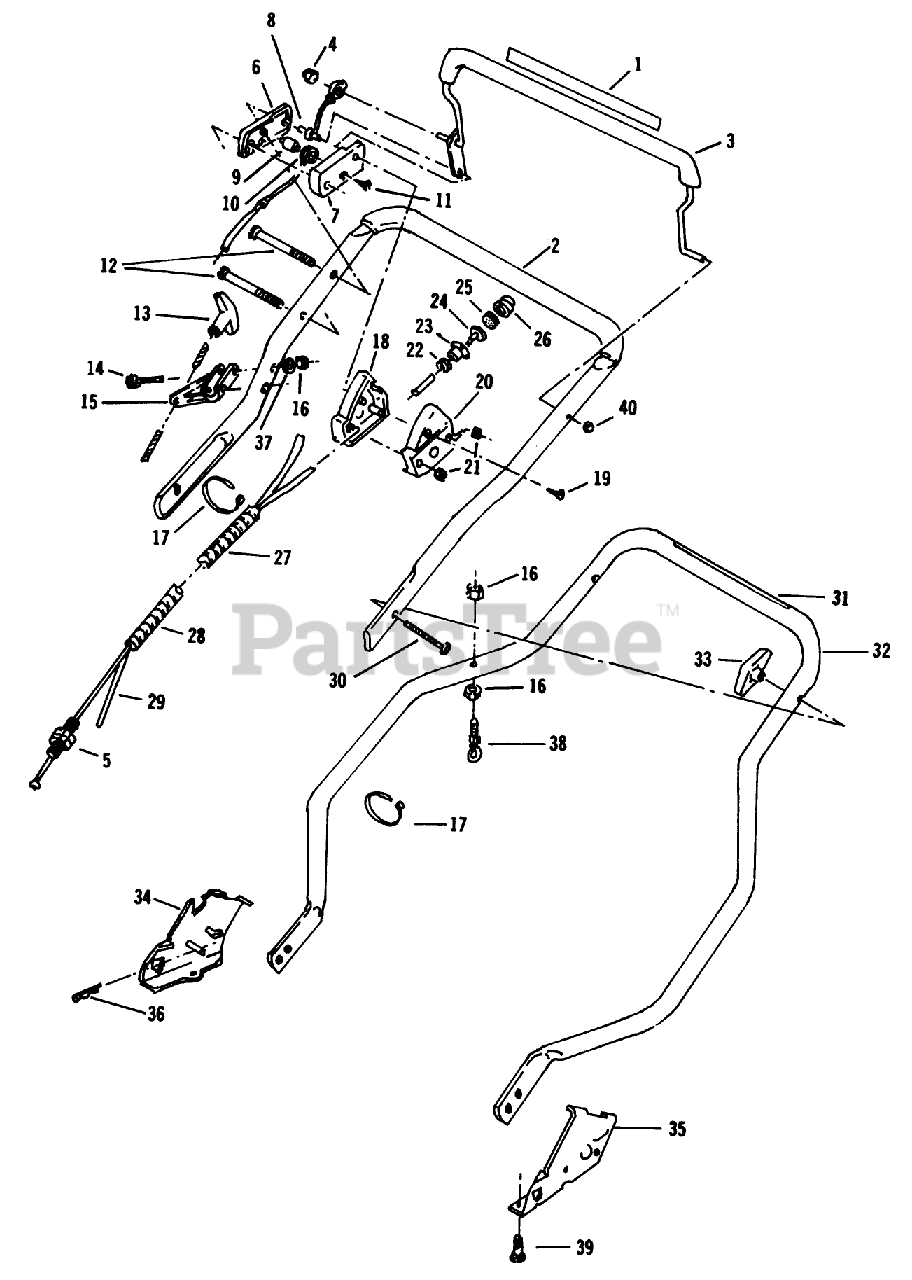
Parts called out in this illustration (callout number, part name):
4	NUT ACORN
8	COLUMN
9	PIN SKF
11	SCREW
13	HANDLE,STARTER
16	LOCKNUT E
19	SCREW LAWRENCE
21	NUT C/LOCK E
22	LOCKNUT S
25	FILTER S
30	BOLT QUALITY
33	NUT-WING
36	HAIR PIN
37	WASHER
38	EYE BOLT WAS MFG
39	SCREW
